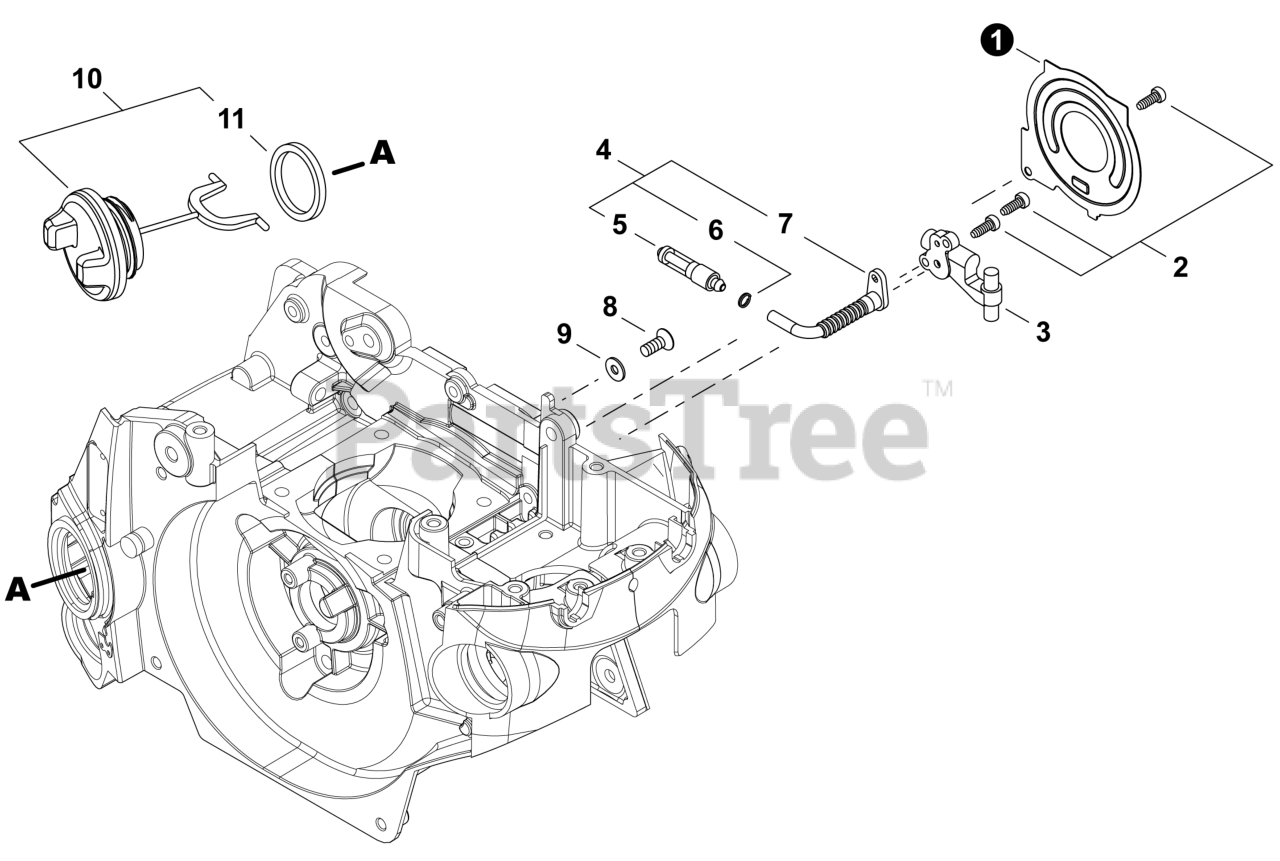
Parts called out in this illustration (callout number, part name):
1	COVER, OILER
2	BOLT, ADHESIVE M4×14
3	AUTO-OILER ASSY
4	FILTER ASSY, OIL
5	FILTER, OIL
6	CLIP Ø6.5 MM
7	PIPE, OIL
8	SCREW 4×8
9	WASHER 4 MM
10	CAP ASSY, OIL
11	GASKET, CAP
